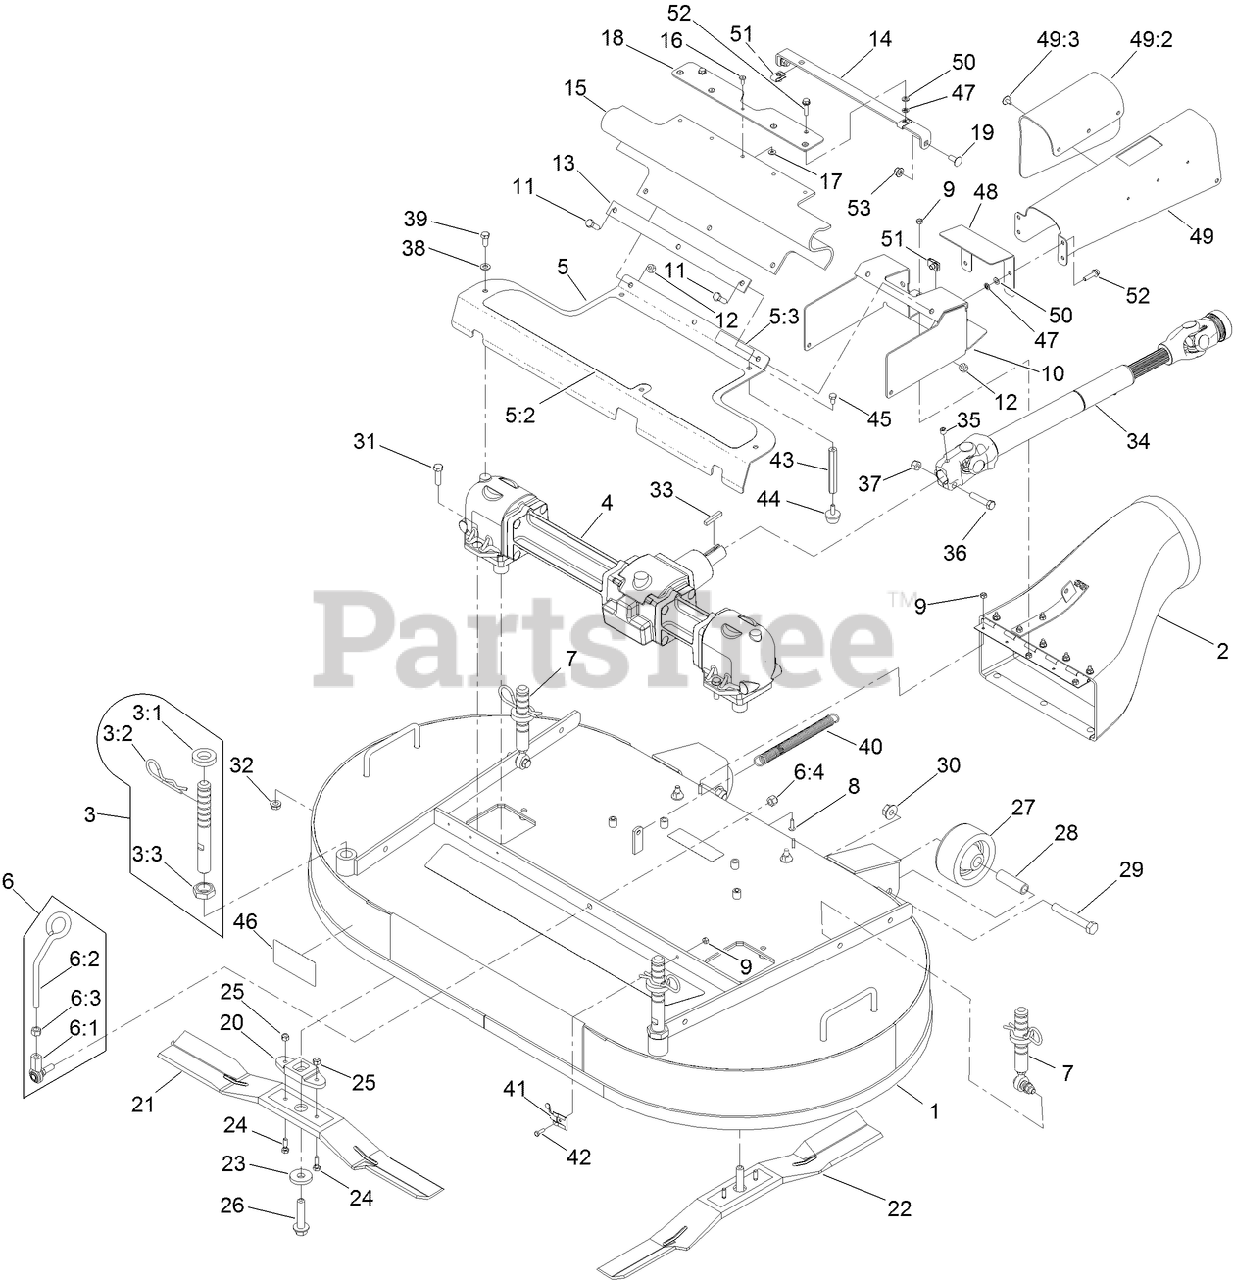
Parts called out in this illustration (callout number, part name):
1	DECK DECAL AND BAFFLE ASM
2	DISCHARGE TUBE ASM
3	FRONT DECK HEIGHT ADJUST ASM
3:1	SPACER-DECK SUPPORT
3:2	PIN-CUT HEIGHT
3:3	NUT-JAM
4	GEAR BOX ASM
5	GEARBOX COVER ASM
5:2	PAD-ANTI SKID
5:3	DECAL-DANGER
6	DECK LATCH ASM
6:1	BALLJOINT-RH
6:2	LATCH-DECK
6:3	NUT-HEX
6:4	NUT-LOCK
7	REAR DECK HEIGHT ADJUST ASM
8	SCREW-HEAD, TRUSS
9	NUT-LOCK, NI
10	GUARD-PTO, FRONT
11	SCREW-HH
12	NUT-LOCK, NI
13	STRAP-DRIVE, LINE COVER
14	MOUNT-GUARD
15	GUARD-PTO
16	RIVET-BLIND
17	WASHER-FLAT
18	PLATE-GUARD
19	SCREW-CARR
20	DRIVER-BLADE
21	BLADE-25IN, RH
22	BLADE-25IN, LH
23	WASHER
24	BOLT-SHEAR
25	NUT-LOCK, NI
26	BOLT-BLADE
27	ROLLER-DECK
28	SPACER-ROLLER
29	SCREW-HH
30	NUT-HHF
31	SCREW-HH
32	NUT-HHF, WHIZ
33	KEY-SQUARE
34	DRIVE SHAFT ASM
35	SCREW-SET, HSH
36	SCREW-HH
37	NUT-LOCK, NI
38	WASHER-PLAIN
39	SCREW-HH
40	SPRING-EXTENSION
41	CLIP-DECK, HOLD UP ROD
43	STAND-OFF
44	BUMPER
45	SCREW-HH
47	NUT-RETAINER
48	GUARD-PTO
49	PTO GUARD ASM
49:2	FLAP-RUBBER
49:3	RIVET-POP
50	WASHER-FLAT
52	SCREW-HHF
53	NUT-HF, NI
